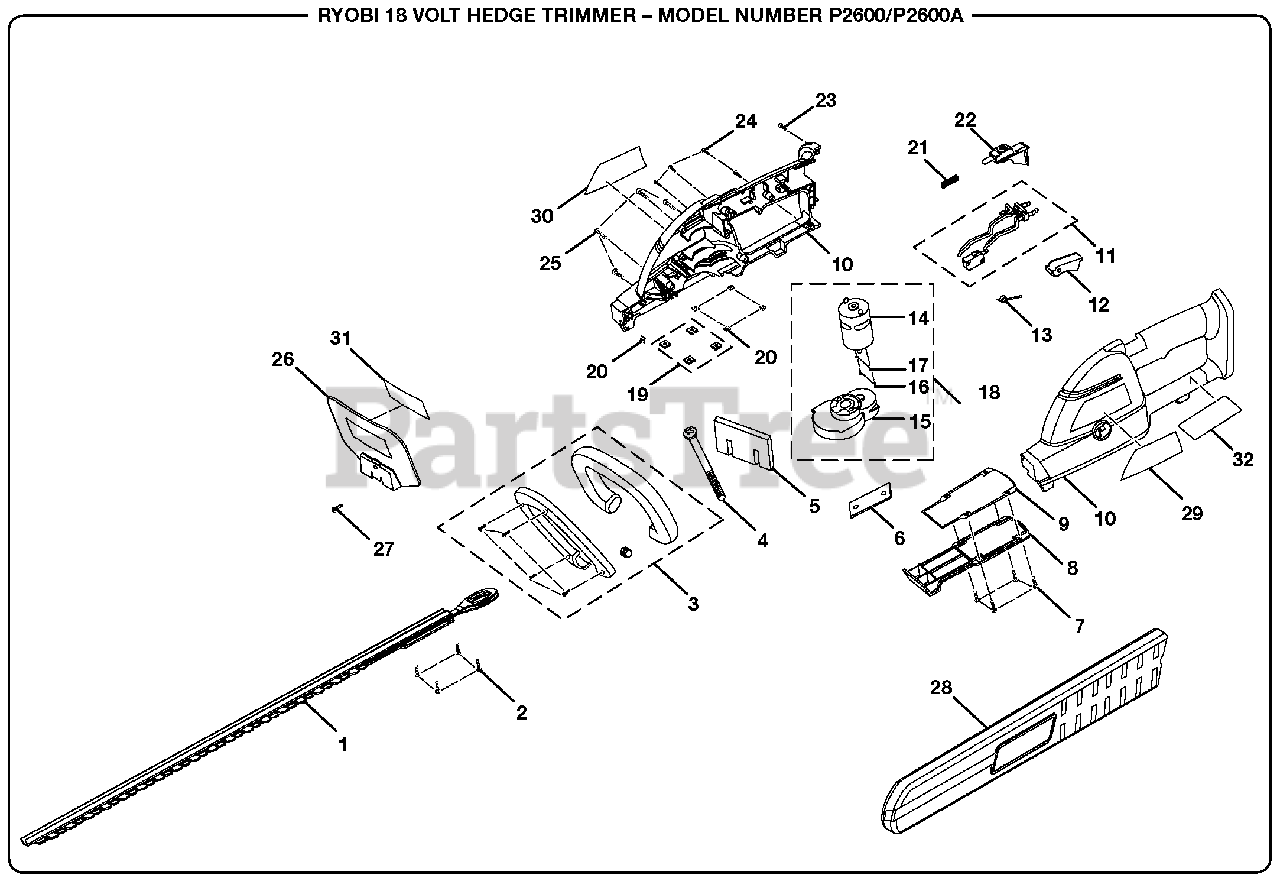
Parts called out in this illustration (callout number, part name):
1	CUTTER BLADE ASSEMBLY
2	SCREW (M4 X 16 mm)
3	HANDLE ASSEMBLY
4	SCREW (M4 X 100 mm)
5	SPONGE SEAL
6	BAR PLATE
7	SCREW (M4 X 12 mm)
8	BLADE COVER
9	RUBBER SEAL
10	HOUSING ASSEMBLY
11	SWITCH ASSEMBLY
13	TRIGGER SPRING
14	MOTOR ASSEMBLY
15	GEAR TRAIN ASSEMBLY
16	SCREW (M4 X 12 mm)
17	RETAINING RING (EXTERNAL)
18	MOTOR & GEAR TRAIN ASSEMBLY (INC. KEY NOS. 14-17)
19	SQUARE NUT (M4 X 15 X 10.9)
20	SQUARE NUT (M4 X 2.2 mm)
21	COMPRESSION SPRING
22	TRIGGER LOCK
23	SCREW (M4 X 12 mm)
24	SCREW (M4 X 16 mm PAN HD.)
25	SCREW (M4 X 22 mm PAN HD,)
26	BLADE GUARD
27	SCREW (M4 X 12 mm)
28	BLADE COVER
29	LOGO LABEL
30	DATA LABEL
31	BLADE GUARD LABEL
